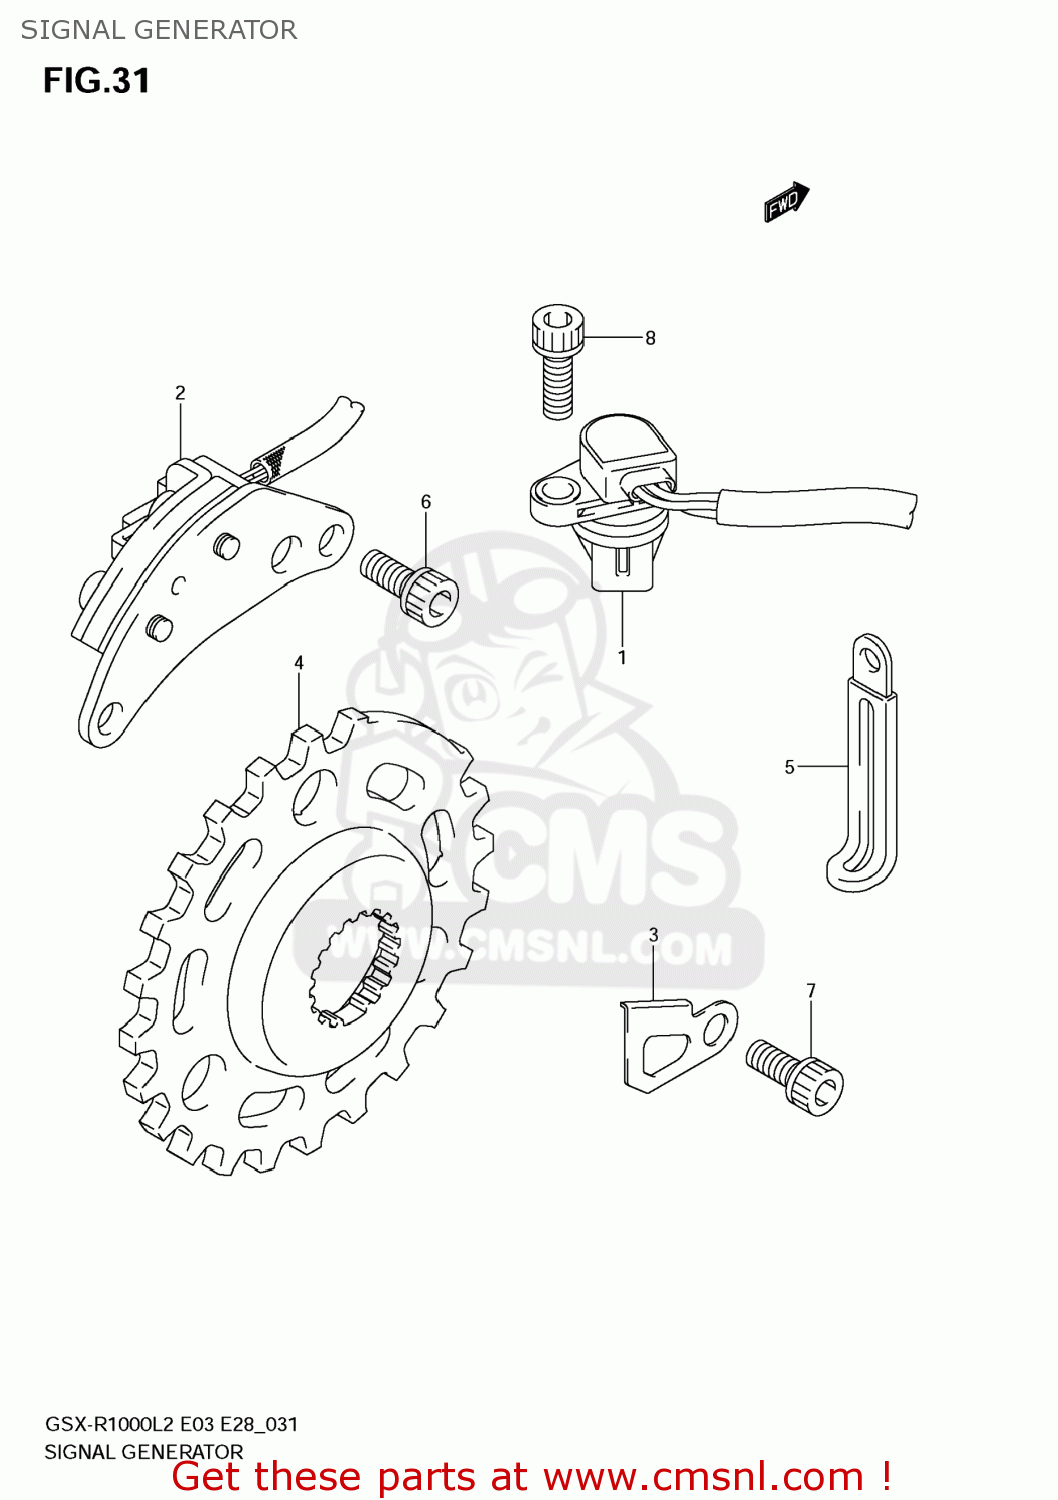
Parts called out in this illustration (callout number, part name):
1	SENSOR ASSY,CAM POSITION
2	STARTER,SIGNAL GENERATOR
3	CLAMP,SIGNAL GENERATORERATOR
4	ROTOR,SIGNAL GENERATOR
5	CLAMP(L:45)
6	BOLT
7	BOLT
8	BOLT
